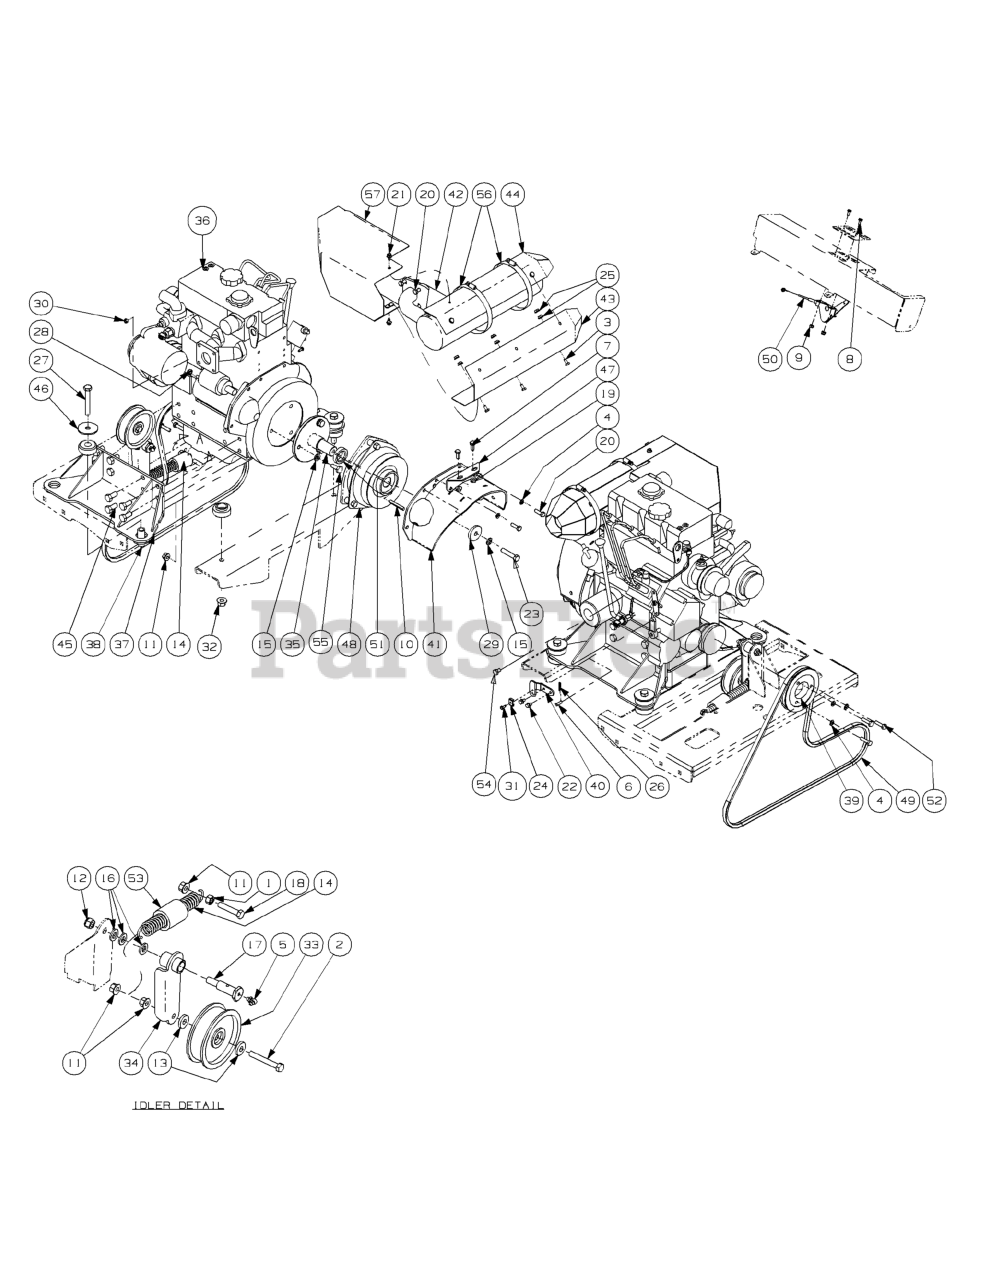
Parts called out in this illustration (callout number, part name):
1	Hex Nut, 3/8-16
2	HHCS, 3/8-16, 2.25
3	Hex Cap Screw, 1/4-20 x 1/2
4	Lock Washer, 5/16
5	Grease Fitting, 90 degree
6	Clevis Pin, 1/4 x 3/4
7	Hex Cap Screw, 5/16-18 x .75
8	Screw, Hex Washer, 10-32 x 1/2
9	Lock Nut, Nylon Insert, 10-32
10	Key, 1/4 x 1/4 x 2.0
11	Flange Lock, Hex Nut, 3/8-16
12	Nylock Nut, 7/16-14
13	Idler Washer
14	Extension Spring, 1.0 OD x 5.00
15	Lock Washer, 7/16
16	Washer, .469 ID x .875 OD x .105
17	Shoulder Bolt
18	Hex Cap Screw, 3/8-16 x 1.75
19	HEX FLANGE NUT
20	Hex Cap Screw, M8-1.25 x 25MM
21	Self Tapping Screw, 1/4-20 x 0.375
22	Screw, M6-1.0 x 12MM
23	Hex Cap Screw, 7/16-20 x 2.00
24	Throttle Clamp
25	Lock Nut, 1/4-20
26	Cotter Pin, .072 x 1.12 Long
27	Hex Cap Screw, 1/2-13 x 3.25
28	Hex Nut, M8 x 1.2, Nylon Top Lock
29	Flat Washer, 7/16 ID x 1.75 OD x .25
30	Nut, M6 x 1, Lock
31	Self Tapping Screw, #10-32 x .500
32	Nut, 1/2-13, FlangeLock
33	Idler Pulley, 3.5 OD
34	Idler Arm Assembly includes:
34	Bearing
35	Drive Shaft
36	Engine, 28.2HP Cat Diesel
37	Engine Mounting Assembly
38	Engine Isolator
39	Transmission Drive Pulley
40	Throttle Cable Mounting Bracket
41	CLutch Retainer Assembly
42	Muffler, 28.2HP Cat Diesel
43	Muffler Cover Assembly, Rear
44	Muffler Cover Assembly, Front
45	HHCS, M12-1.25 x 25MM
46	Washer, .53 ID x 2.13 OD x .134
47	Muffler Mounting Bracket
48	Clutch Brake, GT3.5-CT06D, Diesel
49	V-Belt
50	Throttle Control Cable, 49.0
51	Engine Spacer
52	Hex Cap Screw, M8-1.25 x 30MM
53	Idler Spring
54	Hex Cap Screw, M8-1.25 x 12MM
55	Hex Cap Screw, M10-1.25 x 25MM
56	Worm Clamp, 4.125 - 7.00
57	Exhaust Manifold Shroud Assembly
